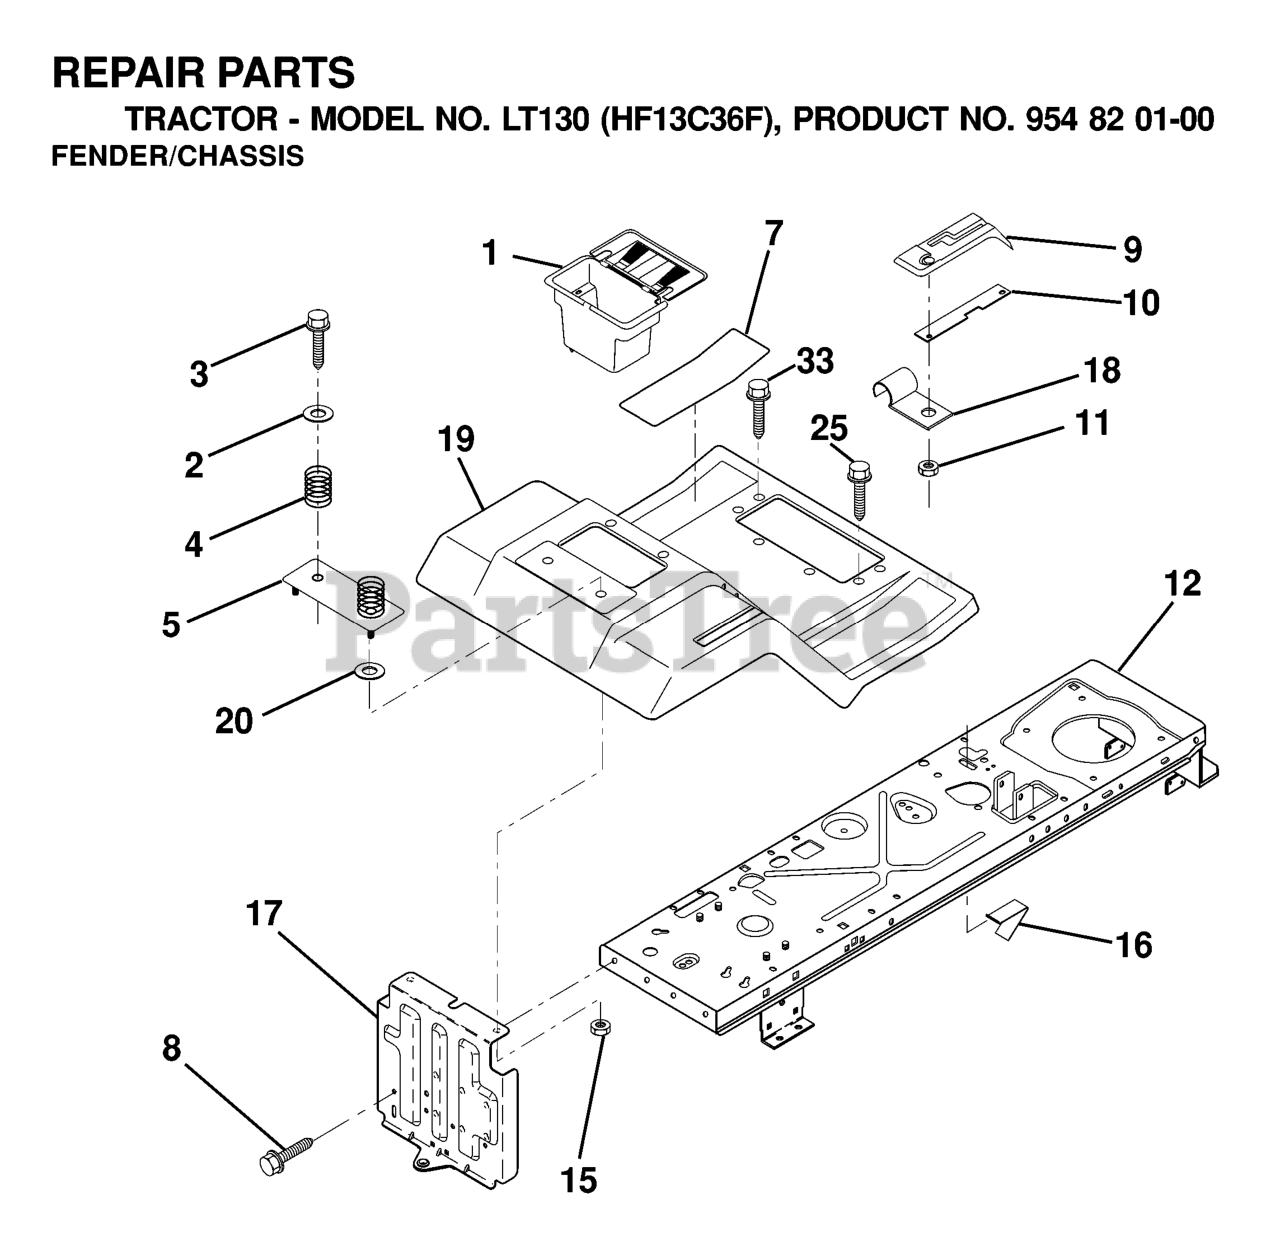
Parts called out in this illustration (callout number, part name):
1	CASE BATTERY MECH HINGE
2	WASHER
3	SCREW
4	SPRING COMPRESSION
5	PLATE ASM BATTERY
7	FOOTREST PAD
8	SCREW.THDROL.5/16-18X3/4.TTY
10	BAR, SHIFT LOCK
11	NUT.PUSH.3/16
15	Nut, Keps Blk Hex 1/4-20 UNC
16	SWITCH ACTUATOR
18	CLIP,INSULATOR
19	FENDER/FOOTREST
20	WASHER
25	Screw Tapping 5/16-18 Unc
33	Screw Hex Wsh Thdroll 5/16-18 x 1
34	SHOULDER BOLT 5/16-18TT
